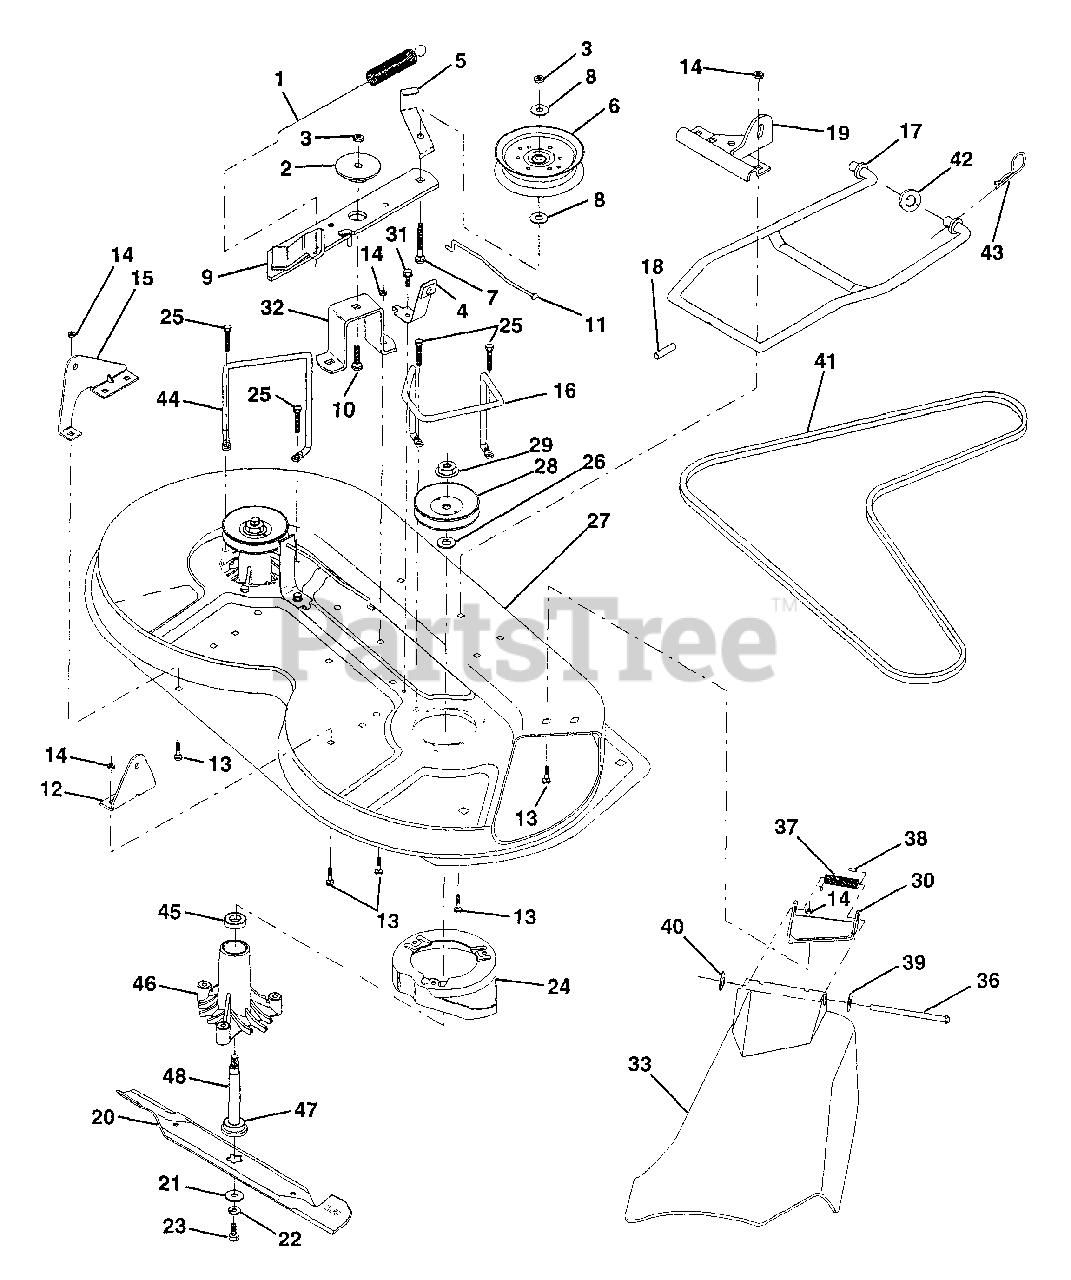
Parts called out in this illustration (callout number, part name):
1	Spring, Mower Clutch
2	Spacer, Retainer
3	Nut, Crownlock
4	Brake Assembly
5	Guide, Belt, Idler
6	Pulley, Flat, Idler
7	Bolt, Carriage 3/8-16 x 2 Grade 5
8	Washer 13/21 x 7/8 x 10 Gauge
9	Arm Assembly, Idler, Mower
10	Bolt, Carriage 3/8-16 x 1
11	Rod, Brake
12	Bracket, Lift, Rear, R.H.
13	Bolt, Carriage 5/16-18 x 5/8
14	Nut, Crownlock 5/16-18
15	Bracket, Lift, Rear, L.H.
16	Keeper, R.H.
17	Link Assembly, Mower Stabilizer
18	Pin, Drive
19	Bracket, Assembly, Front
20	Blade
21	Washer, Hardened
22	Washer, Lock 3/8
23	Bolt 3/8-24 x 1-1/4 Grade 8
24	Stripper
25	Bolt 5/16-18 x 1-1/4
26	Washer .150 Thick
27	Housing Assembly
28	Pulley, Mandrel
29	Nut, Flangelock 9/16
30	Bracket, Assembly, Deflector
31	Screw, Hex Washer Head, Thd., Roll. 5/16-18 x 1/2
32	Arm, Support, Idler, Mower
33	Deflector
36	Rod, Hinge
37	Spring, Torsion, Deflector
38	Cap, Sleeve
39	Washer 11/32 x 5/8 x 16 Gauge
42	Washer 11/32 x 5/8 16 Gauge
43	Retainer, Spring
44	Keeper, L.H.
46	Housing, Mandrel, Vented
48	Shaft, Mandrel
